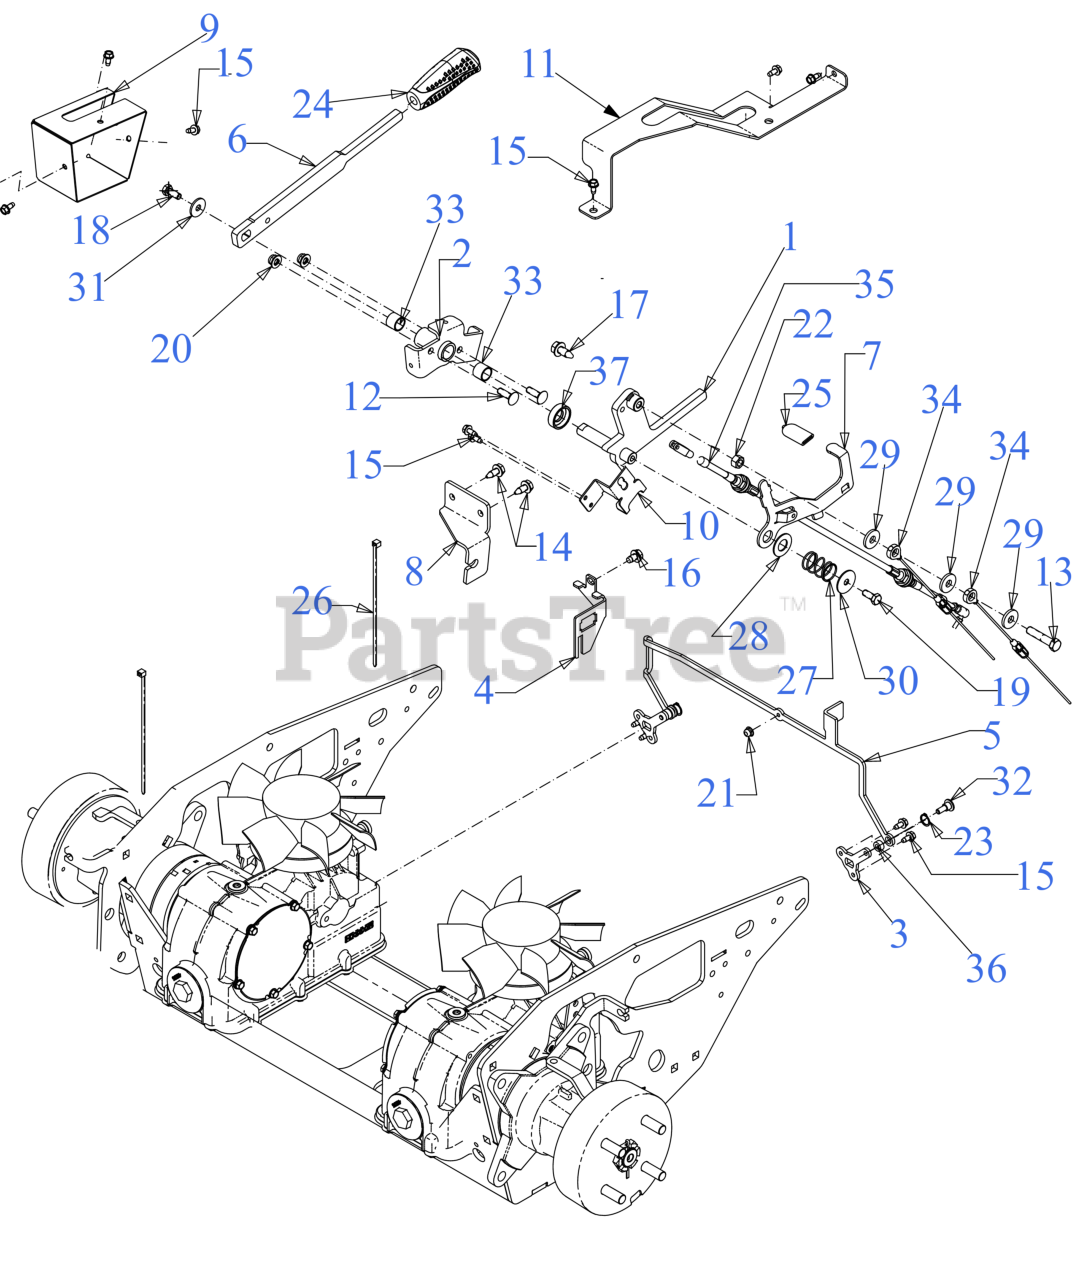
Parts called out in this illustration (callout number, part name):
1	BRAKE SHAFT PIVOT ASSEMBLY
2	PIVOT TUBE ASSEMBLY
3	TRANSMISSION BYPASS LEVER
4	NEUTRAL BRACKET - LAPBAR
5	DUMP VALVE ACCTUATOR BRACKET
7	DUMP VALVE RELEASE LEVER
8	LOWER CABLE MOUNTING BRACKET
10	3-POLE SWITCH BRACKET
11	DUMP LEVER COVER
12	CARRIAGE BOLT 5/16-18 x 1.00
13	HEX SCREW 3/8-16 x 1.75 GR5
14	SCREW 5/16-18 x .750
15	SCREW 1/4-20 X.500
16	SCREW 5/16-18 x .500
17	HEX SCREW WASH TT 3/8-16 x .875
18	SCREW 5/16-18 x .750
19	SCREW 5/16-18 x .75 GR5
20	FLANGE LOCK NUT 5/16-18
23	SNAP RING FOR .562 DIA SHAFT
25	SEAT ADJUSTER GRIP
26	7" CABLE TIE
27	COMPRESSION SPRING .844X.970X1.50
28	FLAT WASHER .640ID X1.24OD x .06
29	FLAT WASHER .385 x 1.00 x .135
30	FLAT WASHER .322 ID x 1.25 x .060
31	FLAT WASHER 1.0 OD:.331 ID
32	SHOULDER SCREW .375X.280:1/4-14
33	SLEEVE BEARING
34	BRAKE CABLE
35	NEUTRAL CONTROL CABLE
